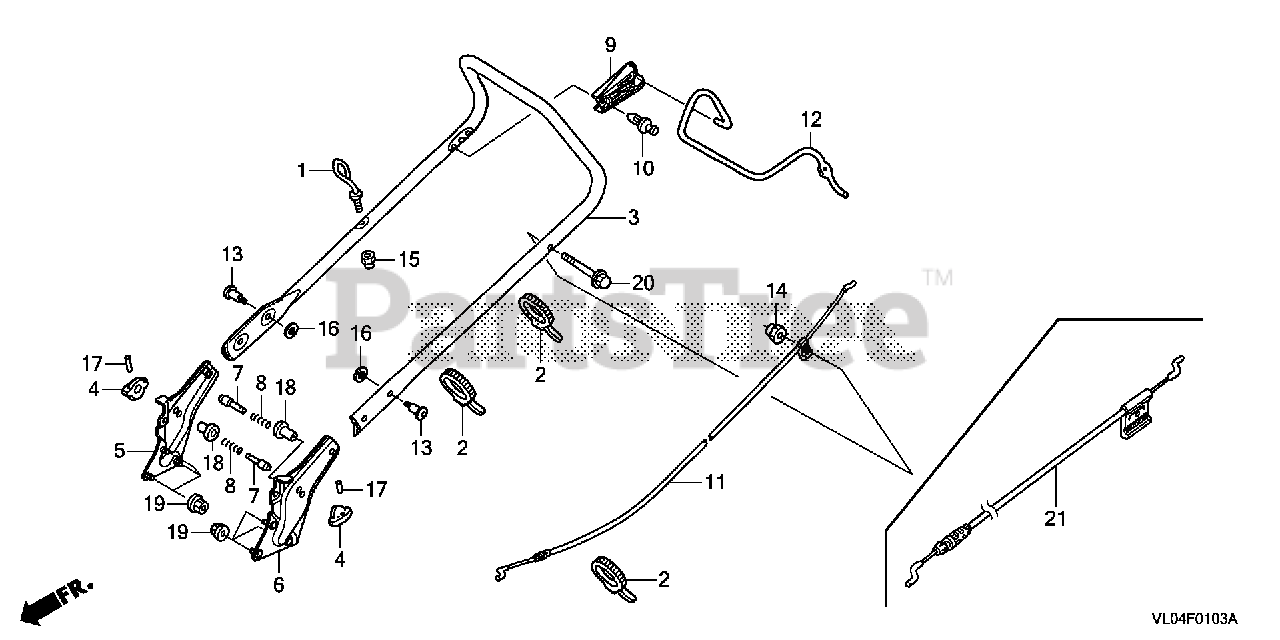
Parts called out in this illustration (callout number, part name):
1	GUIDE, ROPE
2	TIE, CABLE (157.5MM)
3	PIPE, HANDLE *NH105* (MAT BLACK)
4	GRIP, HANDLE JOINT *NH164* (GRIP GRAY)
5	STAY, R. HANDLE
6	STAY, L. HANDLE
7	PIN (8MM)
8	SPRING, HANDLE ADJUSTING
9	STOPPER, LEVER
11	CABLE, BRAKE
12	LEVER, BRAKE *NH105* (MAT BLACK)
13	BOLT, SPECIAL (8X32)
14	NUT, NYLON LOCK (6MM)
15	NUT, NYLON LOCK (6MM)
16	WASHER (25MM)
17	PIN, COILED (2X12)
18	COLLAR, HANDLE HEIGHT ADJUSTING
19	NUT, FLANGE (8MM)
20	BOLT, FLANGE (6X45)
